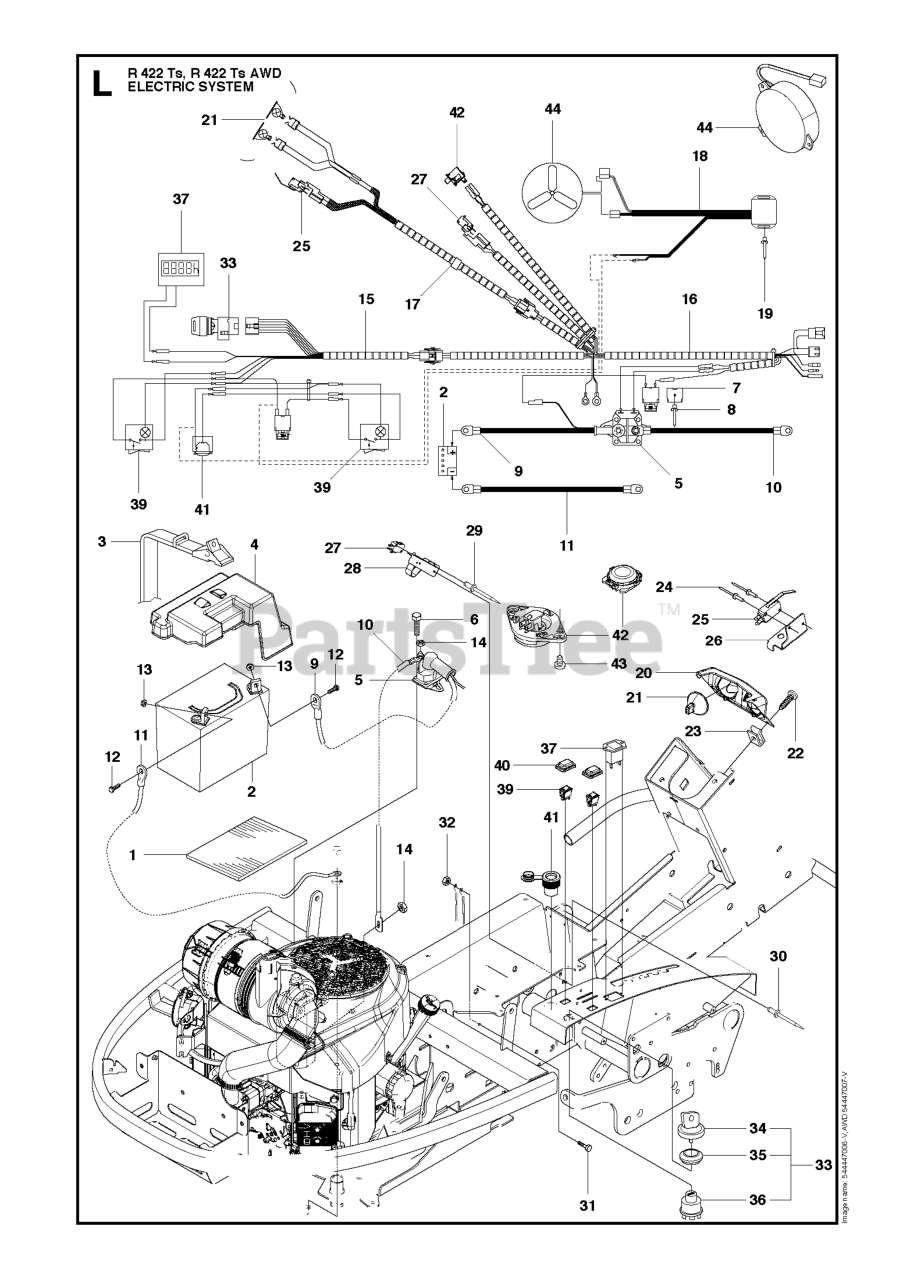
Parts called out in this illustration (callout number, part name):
7	CLIP FUSE
8	RIVET POP
12	SCREW EHHM
25	MICRO SWITCH
31	BOLT
32	NUT
37	HOUR METER
43	SCREW
